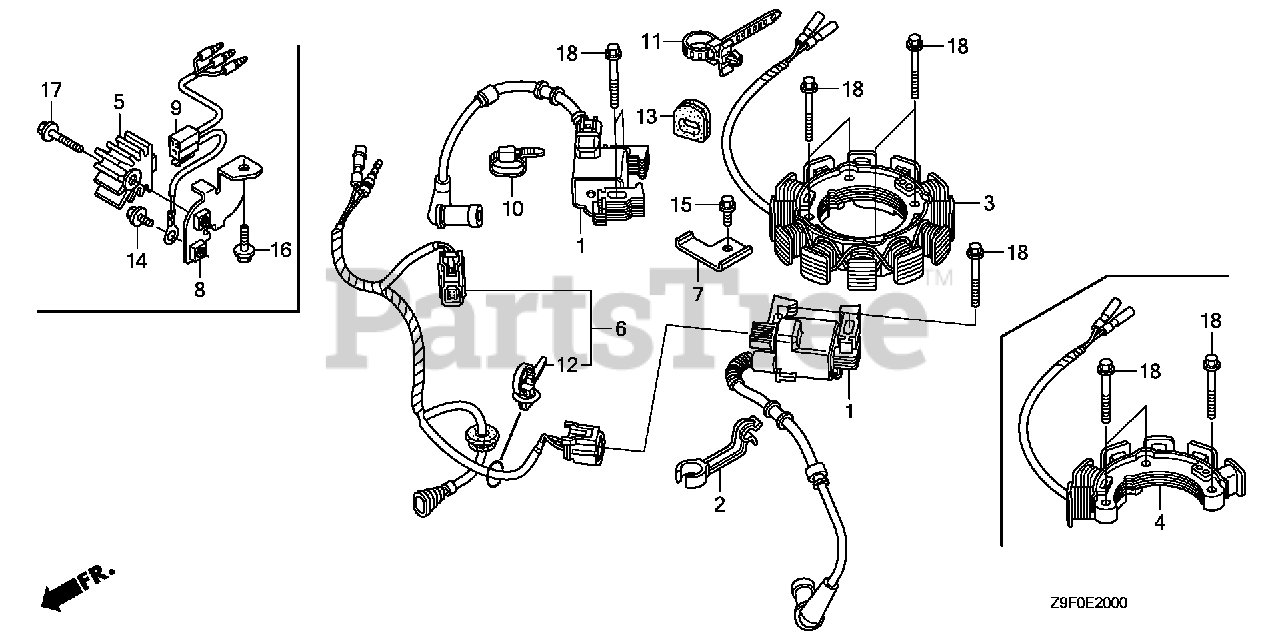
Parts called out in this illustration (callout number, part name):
1	COIL ASSY., IGNITION
2	CLAMP, IGNITION WIRE
3	COIL ASSY., CHARGE (17A)
6	WIRE HARNESS ASSY., ENGINE
7	BRACKET, HARNESS
10	BAND, WIRE (95MM)
11	STRAP, CABLE (105MM) (BLACK)
12	CLIP, HARNESS BAND (145MM) (BLACK)
13	GROMMET, CORD
15	BOLT, FLANGE (6X12)
18	BOLT, FLANGE (6X32)
